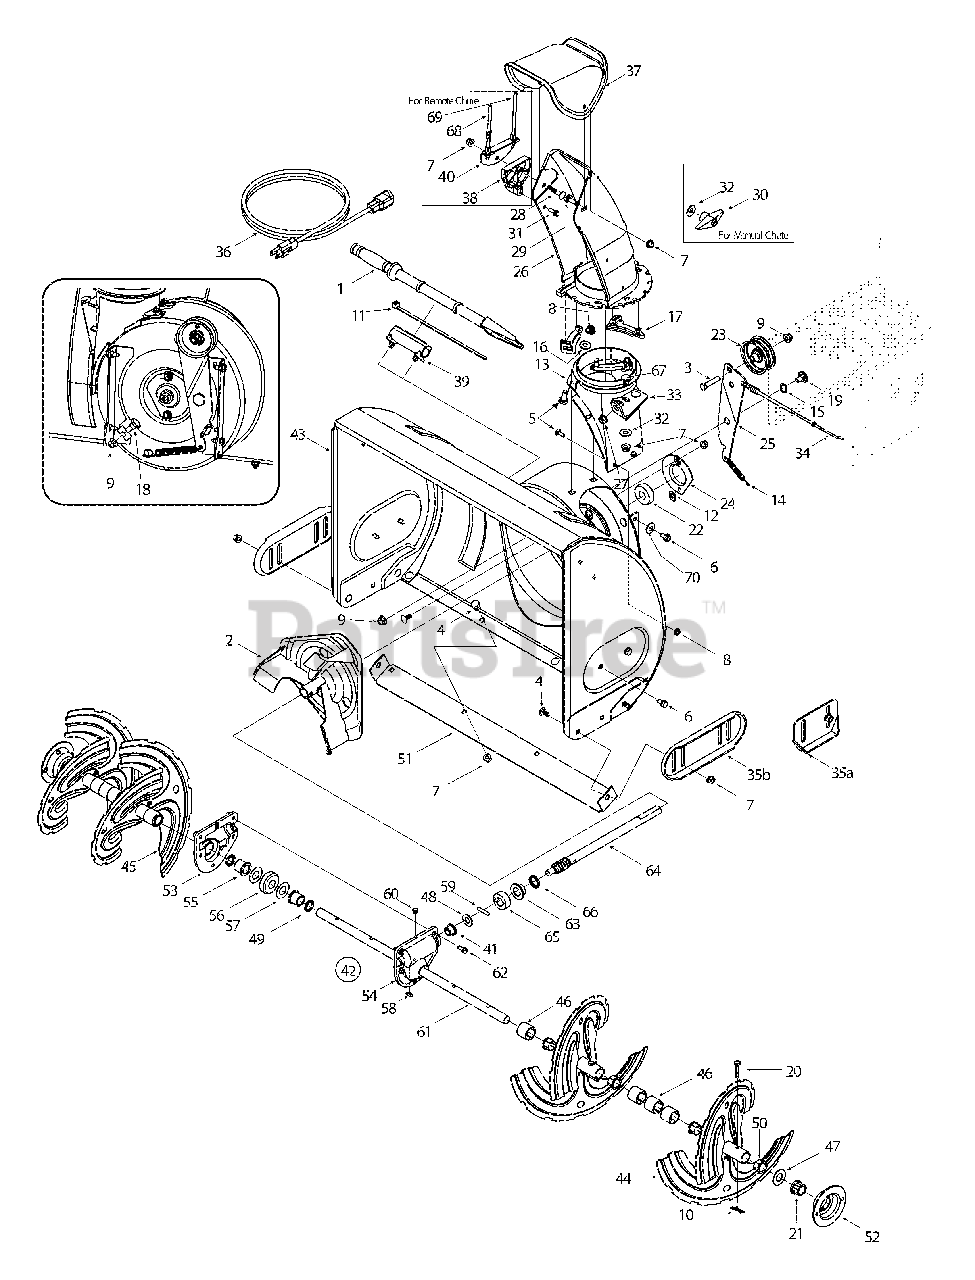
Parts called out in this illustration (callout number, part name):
1	Clean Out Tool
3	Screw, 3/8-16 x 1.75, Gr5, Std
4	Bolt, Carriage, 5/16-18 x.750 Gr1
5	Screw, Carriage, 1/4-20 x.75, Gr5
6	Screw, 5/16-12 x 0.750
7	Nut, Flange Lock, Nylon, 5/16-18, Gr F
8	Nut, Flange Lock, Nylon, 1/4-20, Gr F
9	Nut, Flange Lock, Nylon, 3/8-16, Gr F
10	Pin, Cotter, Bow Tie
11	Cable, Tie, 3/16 x.05 x 7.4
12	Nut, Push-on,.25 Dia
13	Chute, Adapter 5" Dia
14	Spring, Extension,.38 OD x 3.6
15	Washer, Wave,.625 x.885 x.015
16	Washer, Flat,.25 x.630 x.0515
17	Keeper, Flange
18	Screw, Shoulder,.498 x.340, 3/8-16
19	Screw, Shoulder,.625 x.17, 3/8-16
20	Pin, Shear,.25 x1.50, Gr2
21	Bearing, Hex Flange x.75 ID
22	Bearing, Ball,.75 ID x 1.85 OD
23	Pulley, Idler, Flat 2.75 OD
24	Housing, Bearing, 1.85 ID
26	Chute Assembly, Lower, 2-way
27	Plastic Bushing
28	Bolt, Carriage, 5/16-18,.750, Gr1
29	Bolt, Carriage, 5/16-18, 1.00
30	Knob Assembly
31	Screw, 1/4-15 x 0.75
32	Flat Washer,.349 x.879 x.063
34	Auger Clutch Cable, 44.75"
36	Extension Cord, 3-Prong
37	Upper Chute, Manual
38	Cable Guide, Chute Tilt
39	Mount, Clean Out Tool
41	Bearing, Flange,.75 ID x 1.00 OD x.925
42	Gearbox Assembly, Auger, 24"
46	Spacer, 1.25 OD x.75 ID x 1.00
47	Washer, Flat,.76 x 1.49 x.06
48	Washer, Flat,.51 x 1.12
49	Seal, Oil,.750 ID
50	Bushing, Flange,.800 ID x.910 OD
53	Housing Assembly, Auger, RH Reducer
54	Housing Assembly, Auger, LH Reducer
55	Bearing, Flange,.75 ID x 1.00 OD x.975
56	Gear, Worm 20T
57	Washer, Flat,.760 ID x 1.5 OD
58	Key, Hi-pro 3/16 x 5/8
59	Pin, Dowel,.25 OD x 1.2
60	Plug, 1/4 x.437
61	Axle, Auger, 24"
62	Screw, Self-tapping, 1/4-20, 0.750
63	Bearing, Flange,.75 ID x 1.00 OD x.59
64	Shaft, Worm.75 OD
65	Collar, Thrust
66	Seal, Oil,.75 x 1 x.131
67	Carriage Screw, 5/16-18 x 1.00
68	Chute Deflector Cable w/Clip
69	Chute Deflector Control Cable
70	Bell Washer
